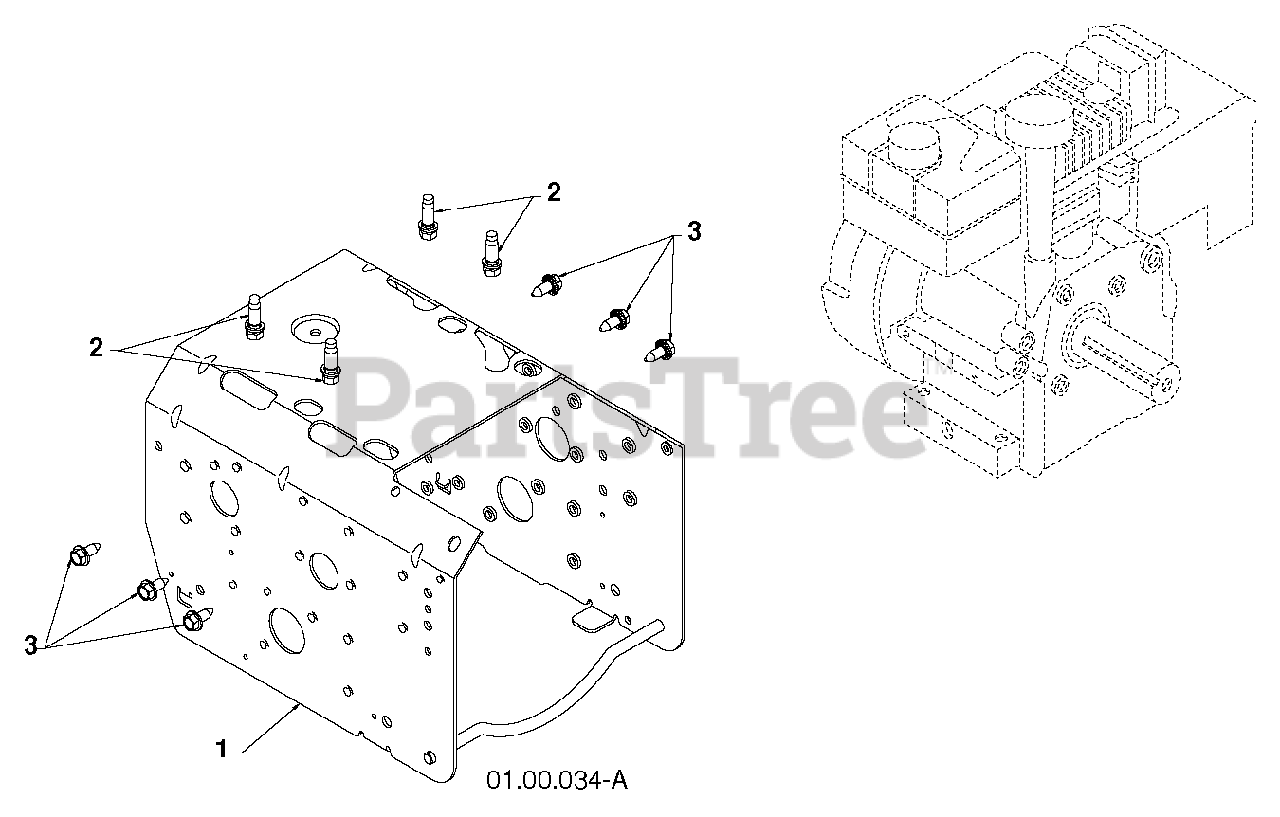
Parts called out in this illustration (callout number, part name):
1	FRAME.WELD.CHAIN.PNT.YELLOW
2	BOLT 3/8-16X1-1/8
3	BOLT.HEX.HD.WASHER.5/16-18X.75
